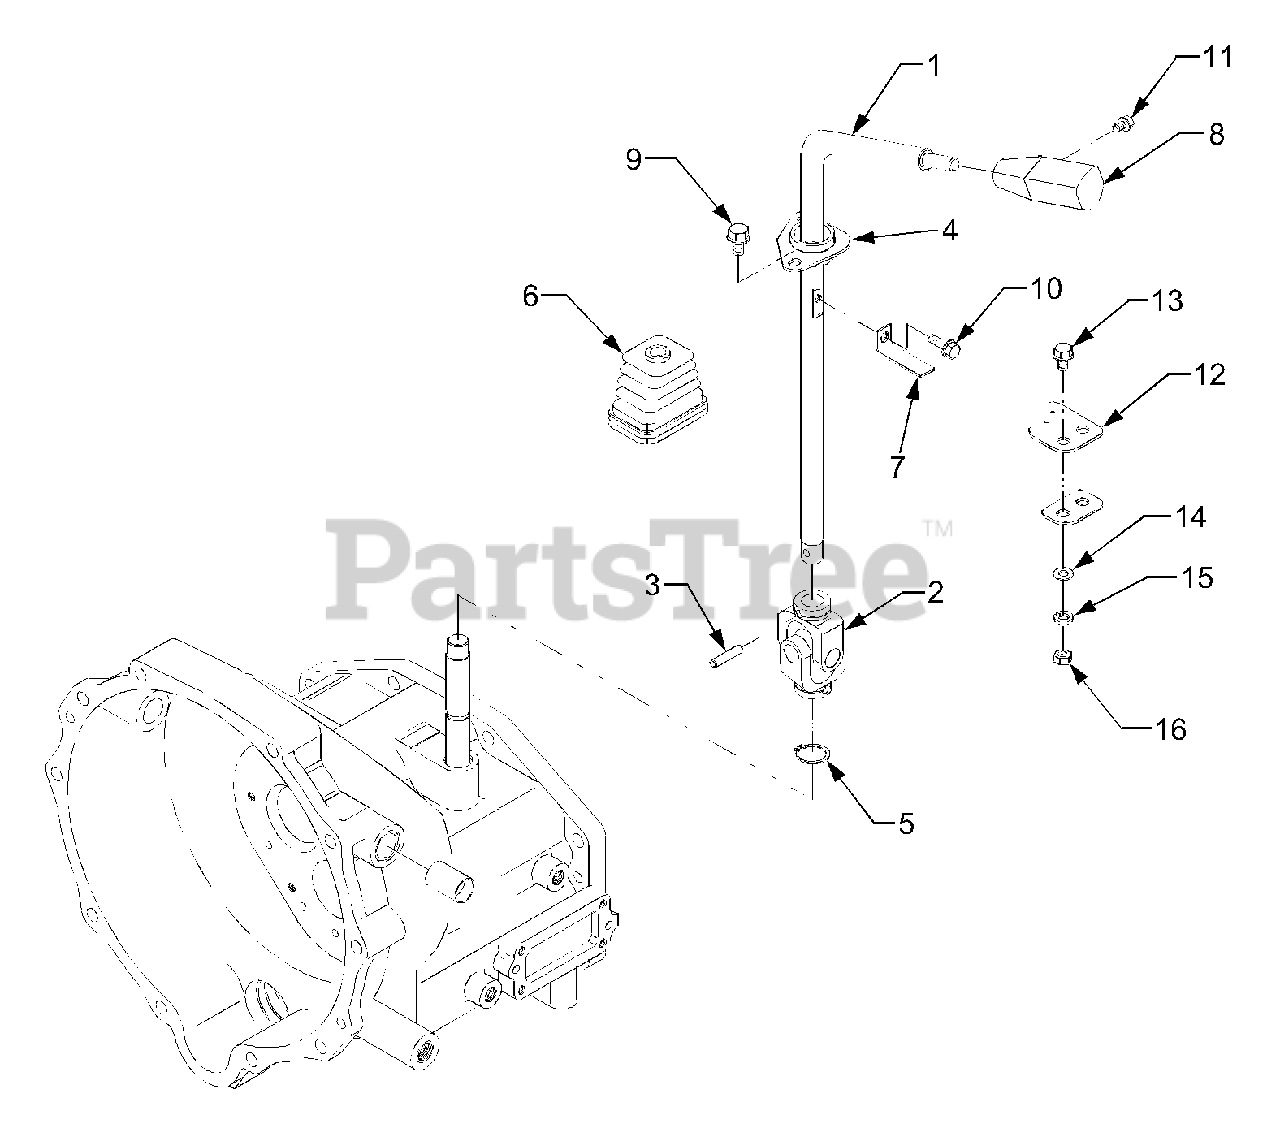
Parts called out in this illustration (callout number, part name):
1	Lever, Shuttle
2	Joint, Universal
3	Pin, Straight
4	Flange, Bearing
6	Boot 1 (Shuttle Lever)
7	Bracket, Switch
8	Grip (Shuttle Lever)
14	Washer, Plain
15	Washer, Spring
